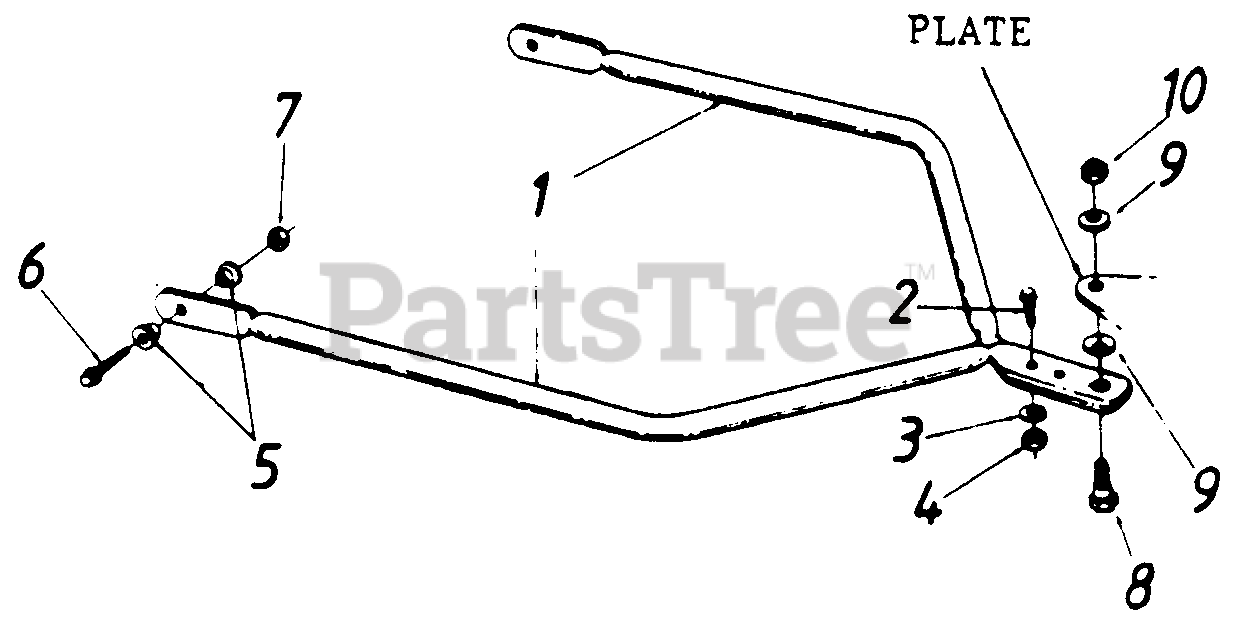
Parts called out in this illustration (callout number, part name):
3	L.-Wash. 1/4" I.D.
4	Hex Nut 1/4-20 Thd.
5	Shoulder Spacer
6	Hex Wash. Hd. Self-Tapp Scr. 5/16-18 x 1.0" Lg.
7	Hex Nut 5/16-18 Thd.
8	Shoulder Bolt
9	Bell-Wash. .39" I.D. x 12"
10	Hex Top Jam Nut 3/8-16 Thd.
